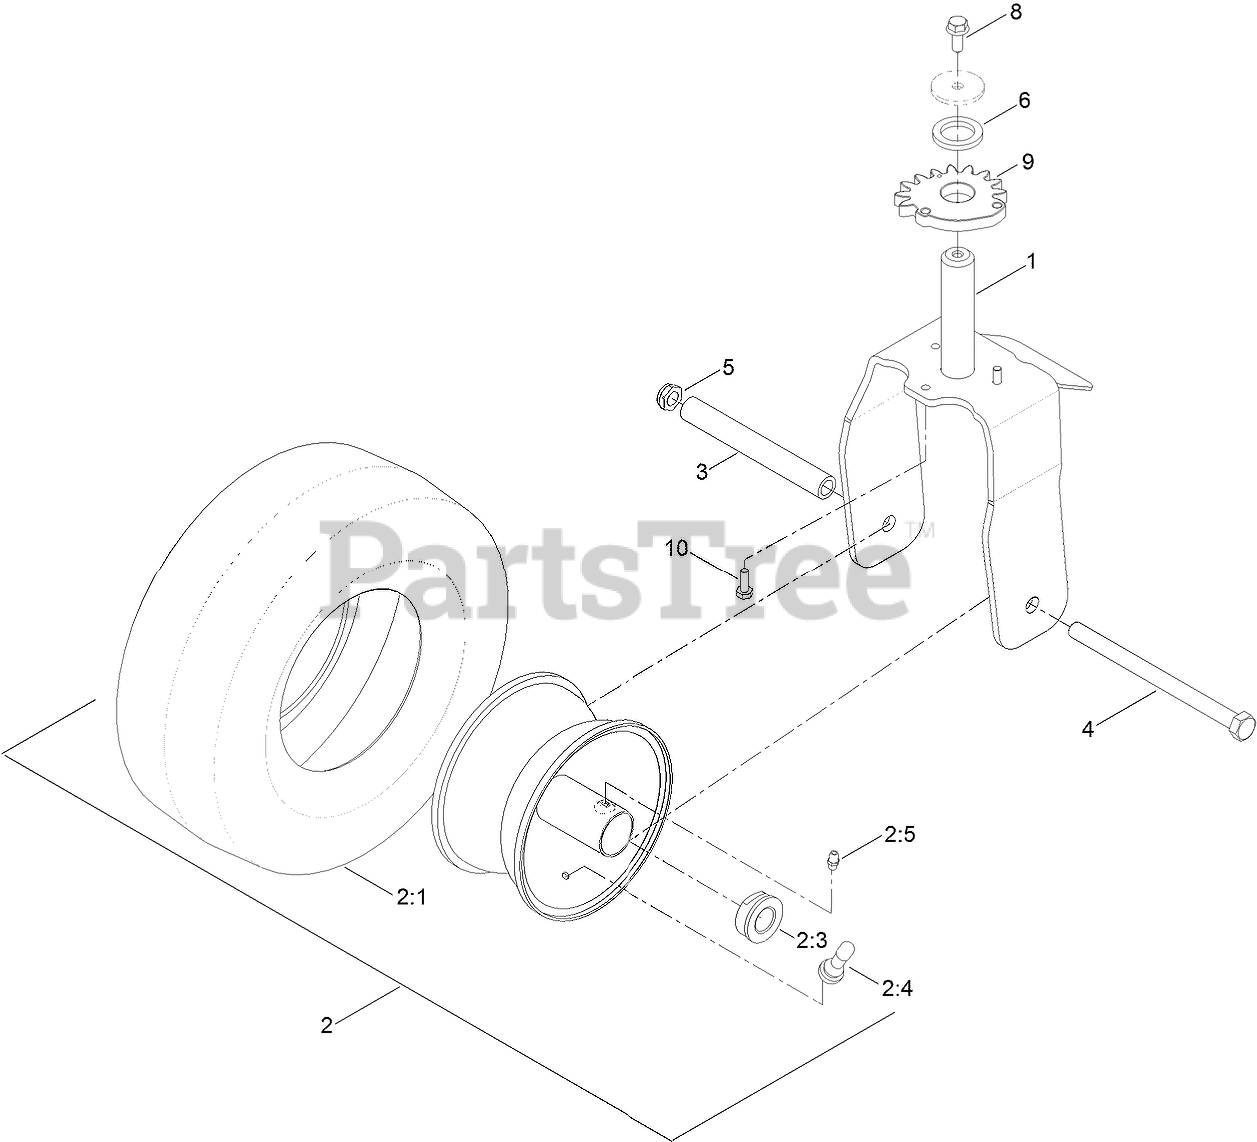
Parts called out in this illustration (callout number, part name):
1	CASTER FORK ASM
2	Caster Wheel ASM
2:3	BUSHING-FLANGE
2:4	STEM-VALVE
2:5	FITTING-GREASE
2:6	TUBE-INNER
3	BUSHING-SPANNER
4	SCREW-HH
5	NUT-LOCK, NI
6	WASHER-THRUST
8	SCREW-HHF
9	GEAR-WHEEL, 15 TEETH
10	SCREW-HH
